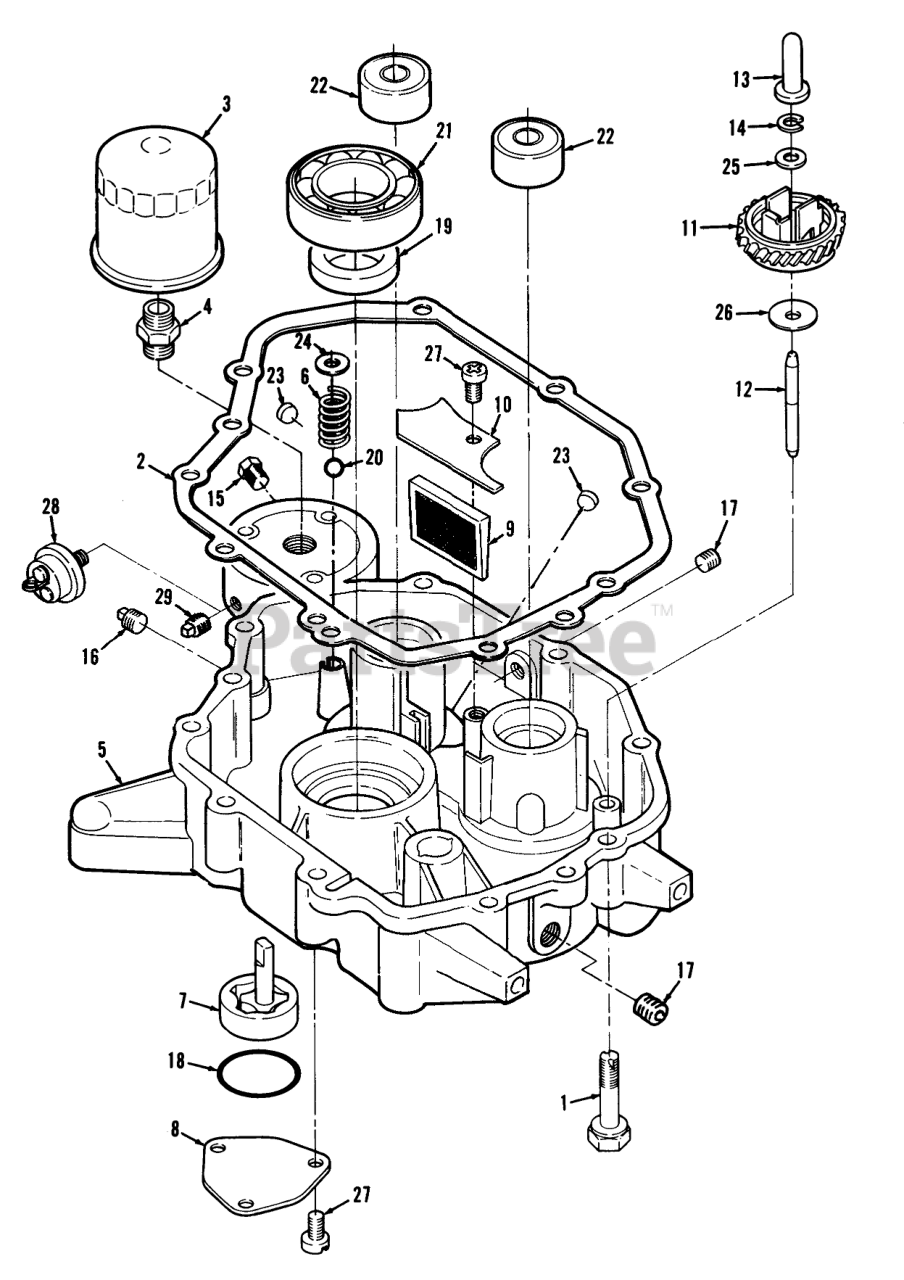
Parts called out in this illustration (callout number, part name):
1	SELF-TAP BOLT SP M8
2	Gasket
3	FILTER
4	ADAPTER
5	BASE-0IL
6	Spring
7	PUMP-OIL
8	COVER-OIL PUMP
9	SCREEN
10	COVER
11	GEAR-GOVERNOR
12	SHAFT-GOVERNOR
13	Sleeve
14	STOP-GOVERNOR
15	PLUG-HEX HD
16	PLUG - SQUARE HEAD
18	RING-O
19	SEAL-OIL CRNKSHFT UP
20	BALL-BEARING
21	BRNG-BALL CRANKSH L
22	BRNG-BALL BAL SHFT L
23	PLUG-CORE HOLE
24	RETAINING-RING
25	WASHER-1.6MM THK
26	WASHER-1MM THK
27	SCREW-M6 X 14
28	SWITCH-OIL PRESSURE
29	Plug
